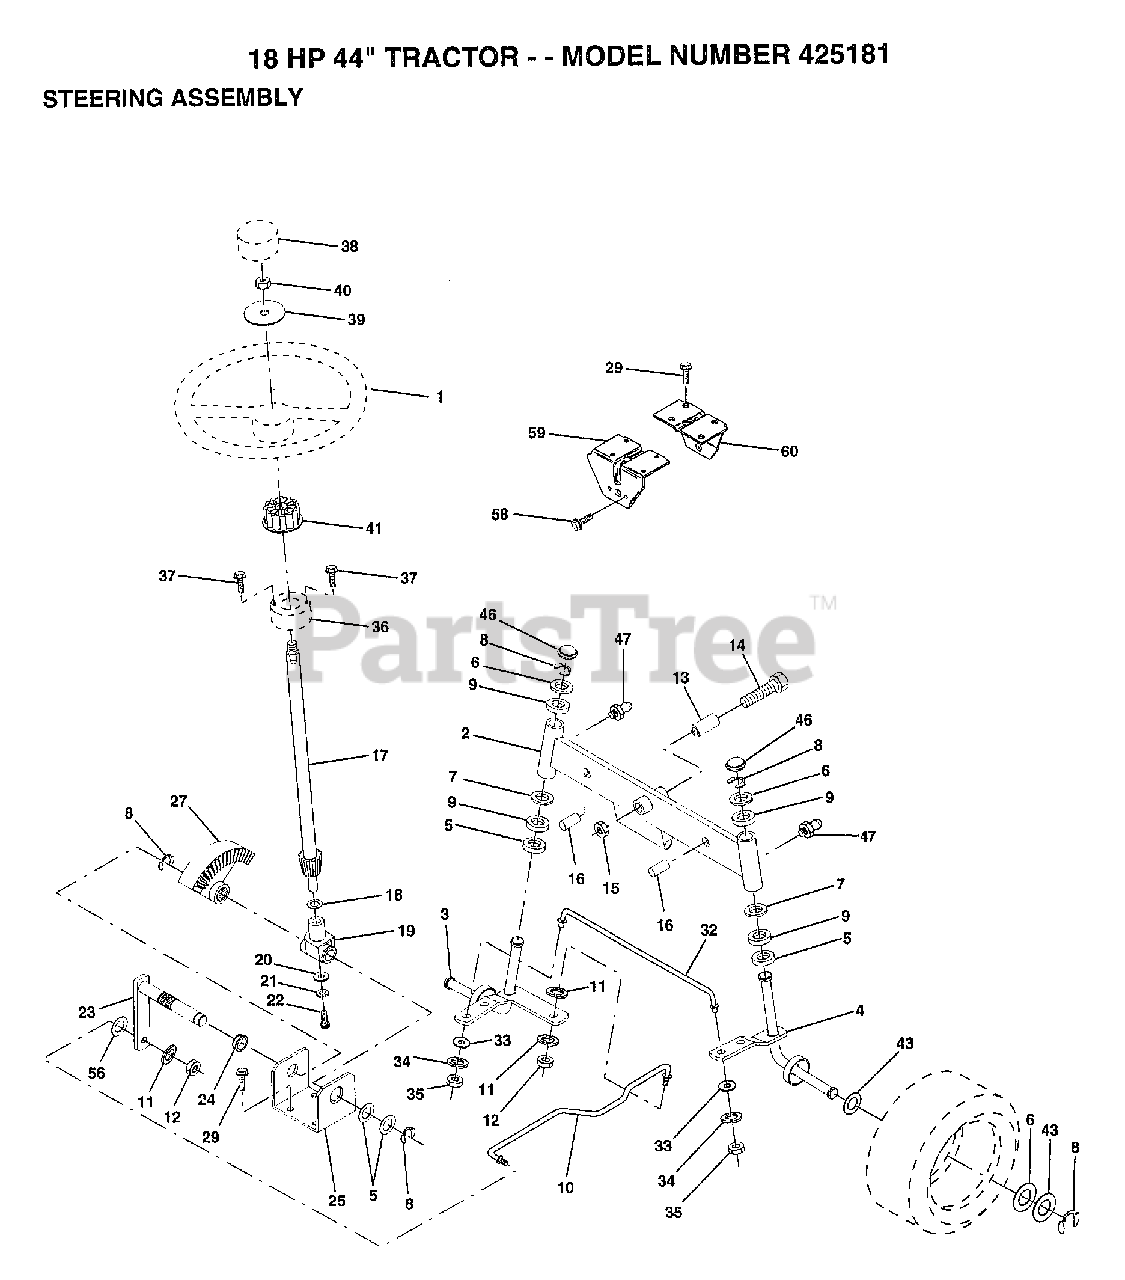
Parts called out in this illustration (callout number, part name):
1	WHEEL STR AYP BLK
2	AXLE ASM FRONT
7	WASHER
9	COL. SRTG. BEAR.
13	BEARING
14	BOLT LT
15	"NUT-LOC,FLANGE LT"
16	AXLE PIN
18	THRUST WASHER
19	SUPPORT.SHAFT
21	LOCKWASHER
22	"SCREW,SPECIAL"
24	NYLINER T
25	"BRKT,STEERING"
26	RING
27	GEAR SECTOR
28	WASHER .T
29	SCREW
30	LOCKWASHER
32	TIE ROD
33	WASHER M
34	LOCKWASHER
35	NUT.LOCK.5/16-24
38	CAP STEER AYP
39	WASHER
41	ADAPTER LT
43	WASHER
44	WASHER
46	CAP
47	ZERK M
56	WASHER
58	SCREW LT
59	SUPPORT-SADDL T
60	SUPPORT.SADDLE.FT
